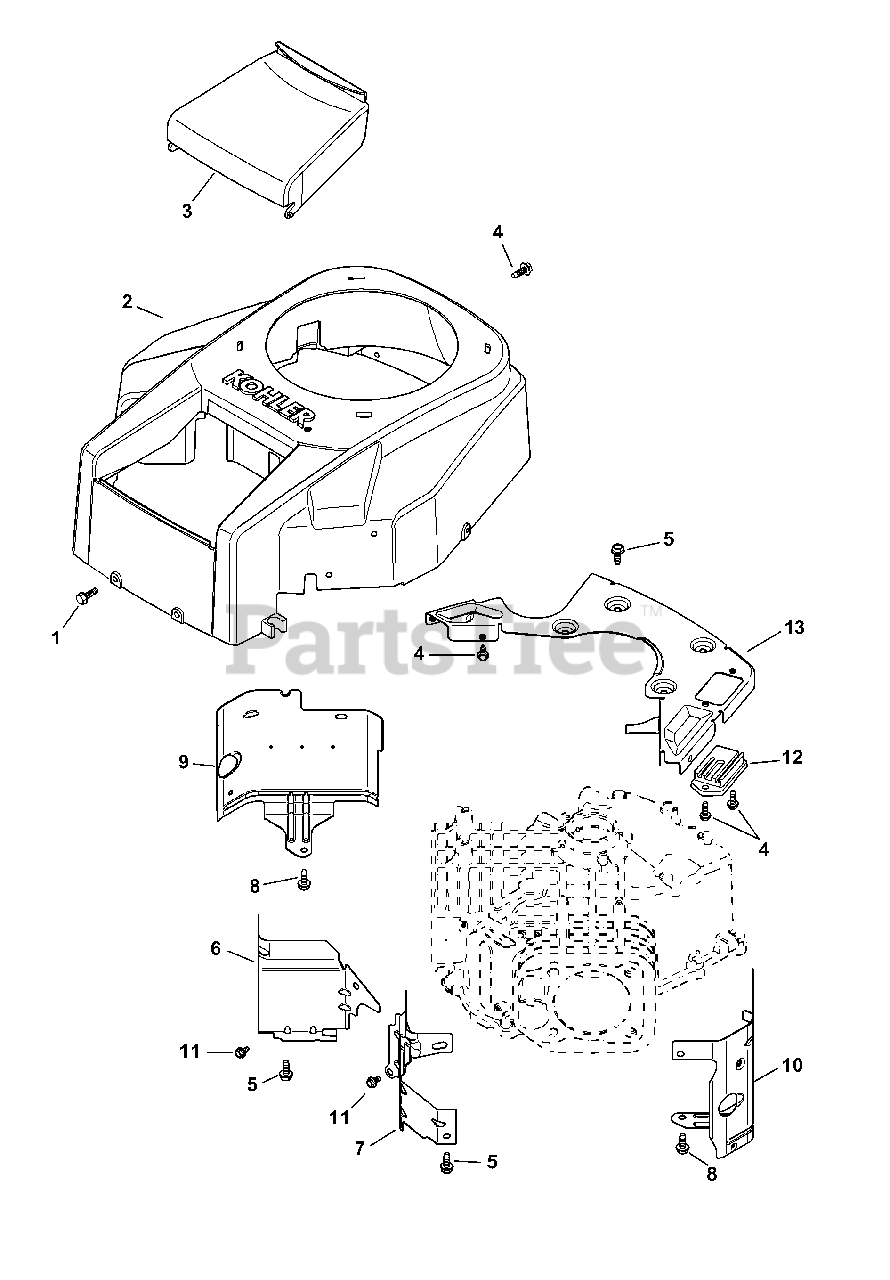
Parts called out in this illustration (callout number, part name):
1	Tap Screw, M6 x 1.7 x 18
2	Housing Blower Kit
3	Air Cleaner Cover
4	Flg. Thd. Frm. Screw, M5 x 0.8 x 16
5	Flg. Thd. Frm. Screw, M6 x 1.0 x 16
6	Valley Baffle - #1 Cylinder
7	Valley Baffle - #2 Cylinder
8	Flng. Thd. Frm. Screw, M6 x 1.0 x 10
9	Cyl Barrel Baffle - #1 Side
10	Cyl Barrel Baffle - #2 Side
11	Flg. Thd. Frm. Screw, M5 x .8 x 10
12	Regulator/Rectifier
13	Backing Plate Kit
